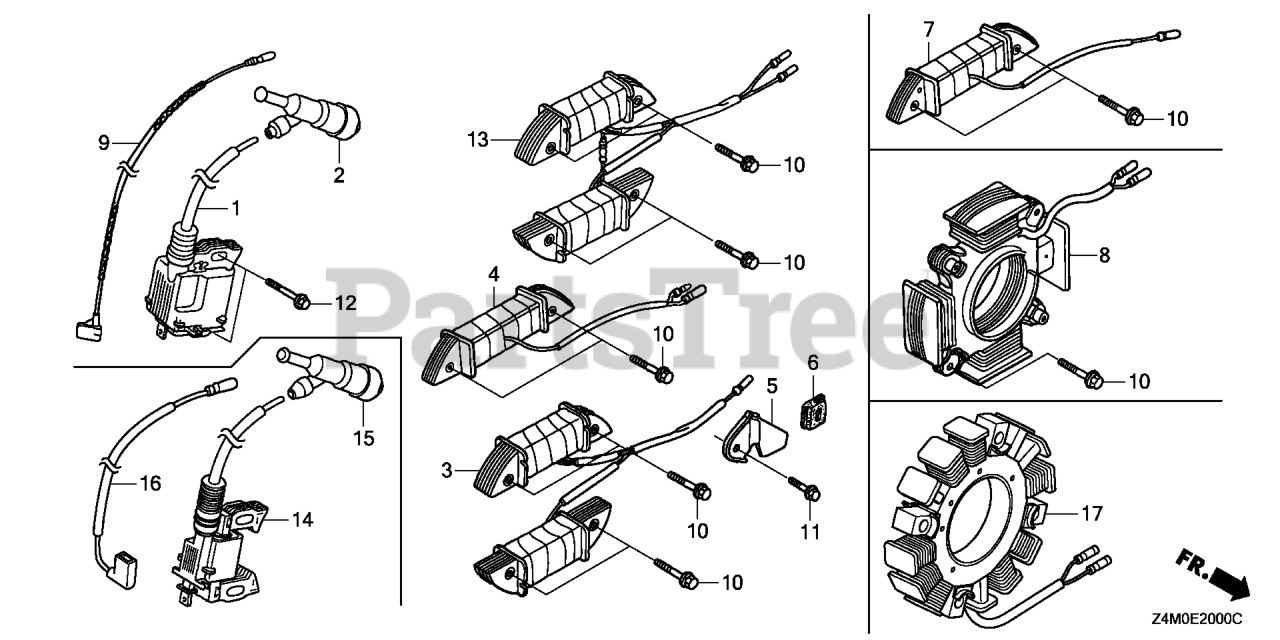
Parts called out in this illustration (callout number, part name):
1	COIL ASSY., IGNITION (TEC)
2	CAP ASSY., NOISE SUPPRESSOR (NGK)
2	CAP ASSY., NOISE SUPPRESSOR (TEC)
9	WIRE, STOP SWITCH (370MM)
12	BOLT, FLANGE (6X25) Use up to Engine SN 2056819.
14	COIL ASSY., IGNITION (TEC)
15	CAP ASSY., NOISE SUPPRESSOR (TEC)
16	WIRE, STOP SWITCH (370MM)
